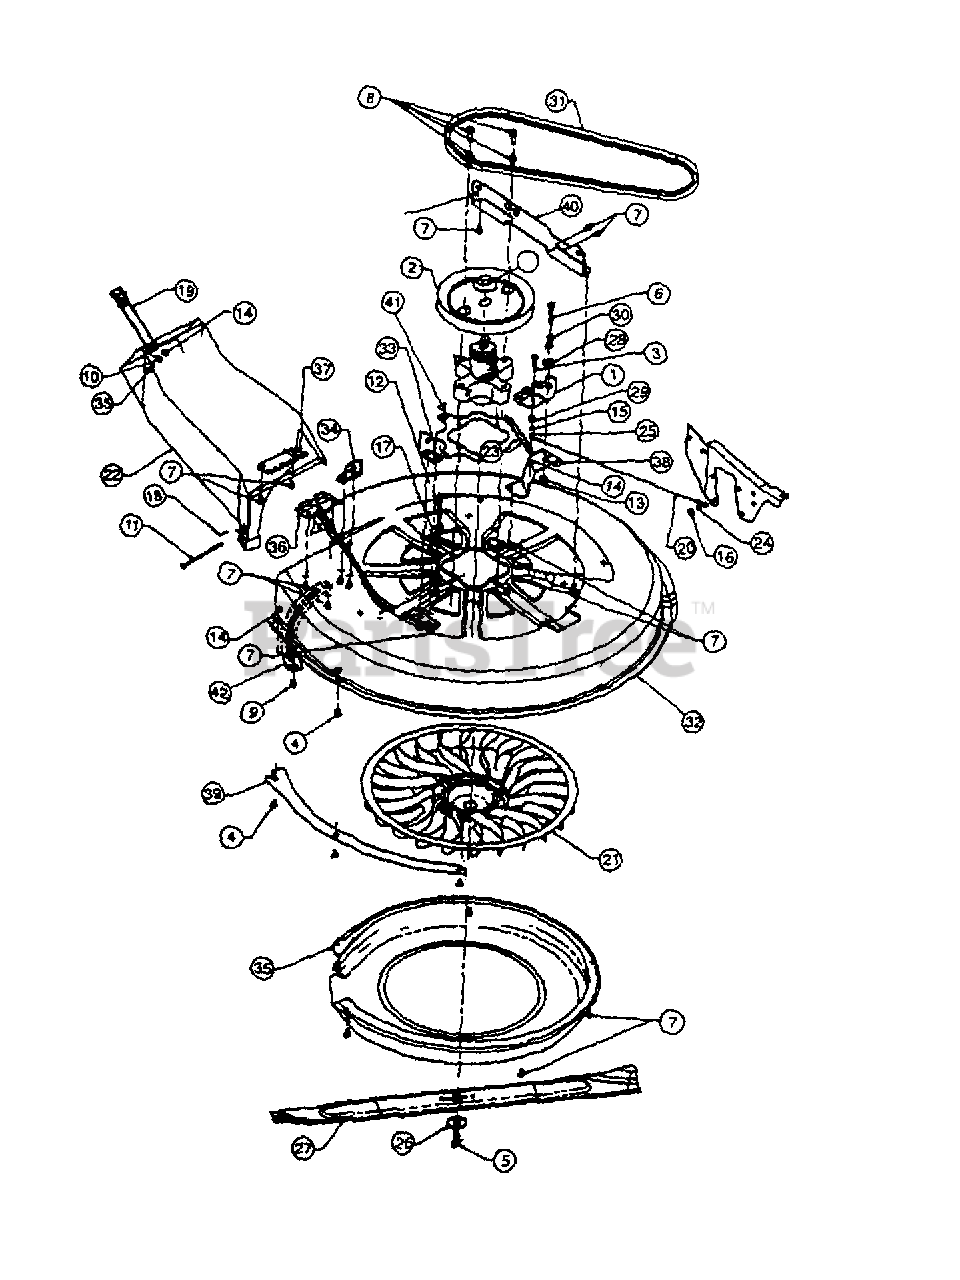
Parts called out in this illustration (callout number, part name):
1	Brake Bracket Assembly.
2	Spindle Assembly. w/Pulley
3	Hex Bolt 1/4-20 x 1.25" Lg.
4	Carriage Scr. 1/4-20 x .62"
5	Hex Bolt 7/16-20 x 1.0"
6	Hex Bolt 5/16-18 x 1.75" Lg.
7	Hex Washer Hd. TT-Tap Scr. 1/4-20 x .5"
8	Hex Washer Hd. TT-Tap Scr. 5/16-18 x 1"
9	Hex Carriage Scr.
10	Hex screw 1/4-20 x .75
11	Clevis Pin 4.42"
12	Belt Guard Pin 3.06"
13	Hex Sems Nut 5/16-18 Thd.
14	Lock Nut 1/4-20
15	Hex Nut 1/4-20
16	Hex Nut 5/16-18 Thd. (Gr. 5)
17	Top Lock Hex Jam Nut 5/16-18
18	Cotter Pin 3/32" Dia.
19	Strap Retainer Assembly.
20	Brake Cable 16.47"
21	Deck Fan
22	Rear Discharge Chute
23	Ext. Spring 5.52" Lg.
24	Flat Washer .344" 1.0. x .62" O.D.
25	Flat Washer .283 x .75 x .030
26	Belle. Washer
27	Blade: 30" x .150 Thk.
28	Shoulder Spacer
29	Spacer
30	Spacer
31	V Belt
34	Deck Hanger Bracket
40	Deck Hanger Bracket
41	Reinf. Plate
42	Chute Support
